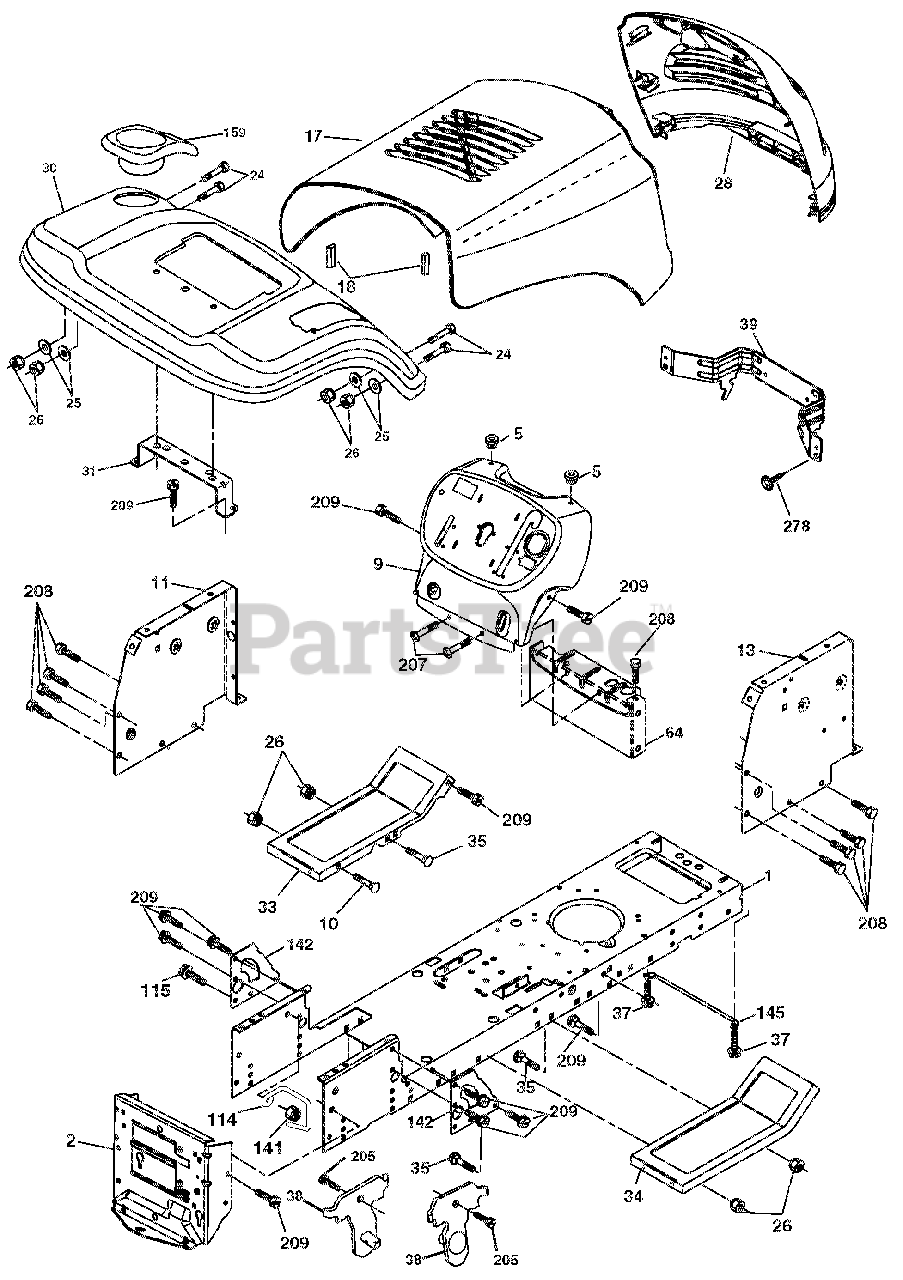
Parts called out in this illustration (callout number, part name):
1	Chassis
2	Drawbar, Stretch
5	Bumper, Hood/Dash
10	Panel Slkscr Dash RH
11	Panel Dash LH
13	Panel Slkscr Dash RH
18	BUMPER.HOOD.LARGE. 1.75"
24	Bolt Fin Hex 3/8-16 unc x 1 Gr
25	Washer 13/32 x 13/16 x 12 Ga.
26	Locknut, Washer Insert 3/8-16
30	FENDER
31	Bracket Fender Repl 109873X
33	FOOTREST LH
34	FOOTREST RH
35	Bolt Rdhd Sht Sqnk 3/8-16 x 3/
37	SCREW.THDROL.5/16-18 X 1/2TYTT
38	Bracket Asm. Pivot Mower
39	Bracket Pivot
64	Dash Lower
114	KEEPER.BELT.REAR
115	Screw 3/8-16 x <
141	Nut, Hex, Flangelock 3/8-16
142	Plate Reinforcement
145	ROD.PIVOT.HOOD
159	CUPHOLDER
205	Screw Thdrol 3/8-16 x 1/2
207	Screw 5/16-18 x 1/2
208	SCREW.THDROL.3/8-16X1/2.TYT.BL
209	SCREW.HEXWSH THDR3/8-16X3/4.BL
212	Insert Lens Reflect
